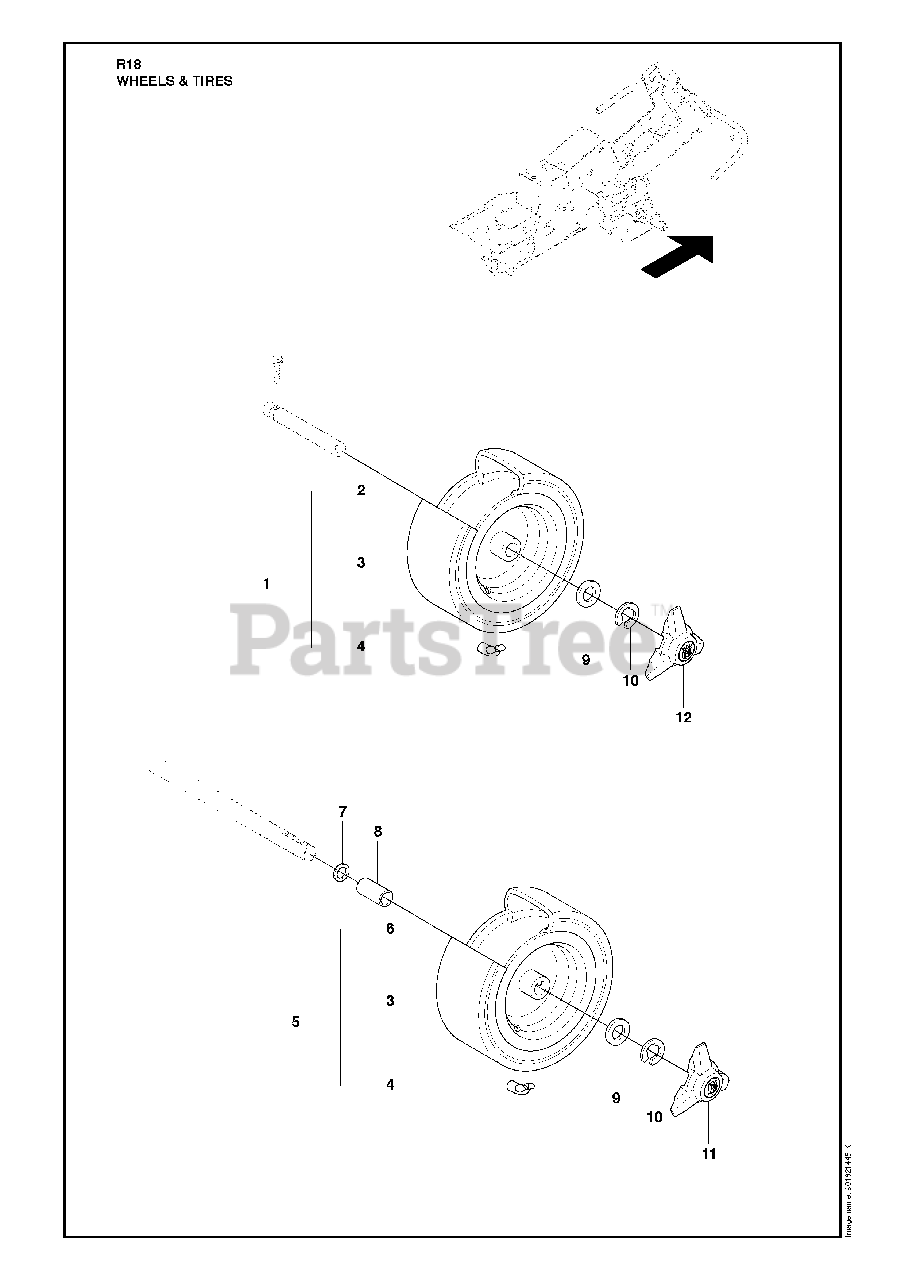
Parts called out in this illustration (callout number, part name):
3	TIRE
4	VALVE
7	TIRE
8	VALVE
10	SPACE SLEEVE
12	RETAINING RING
